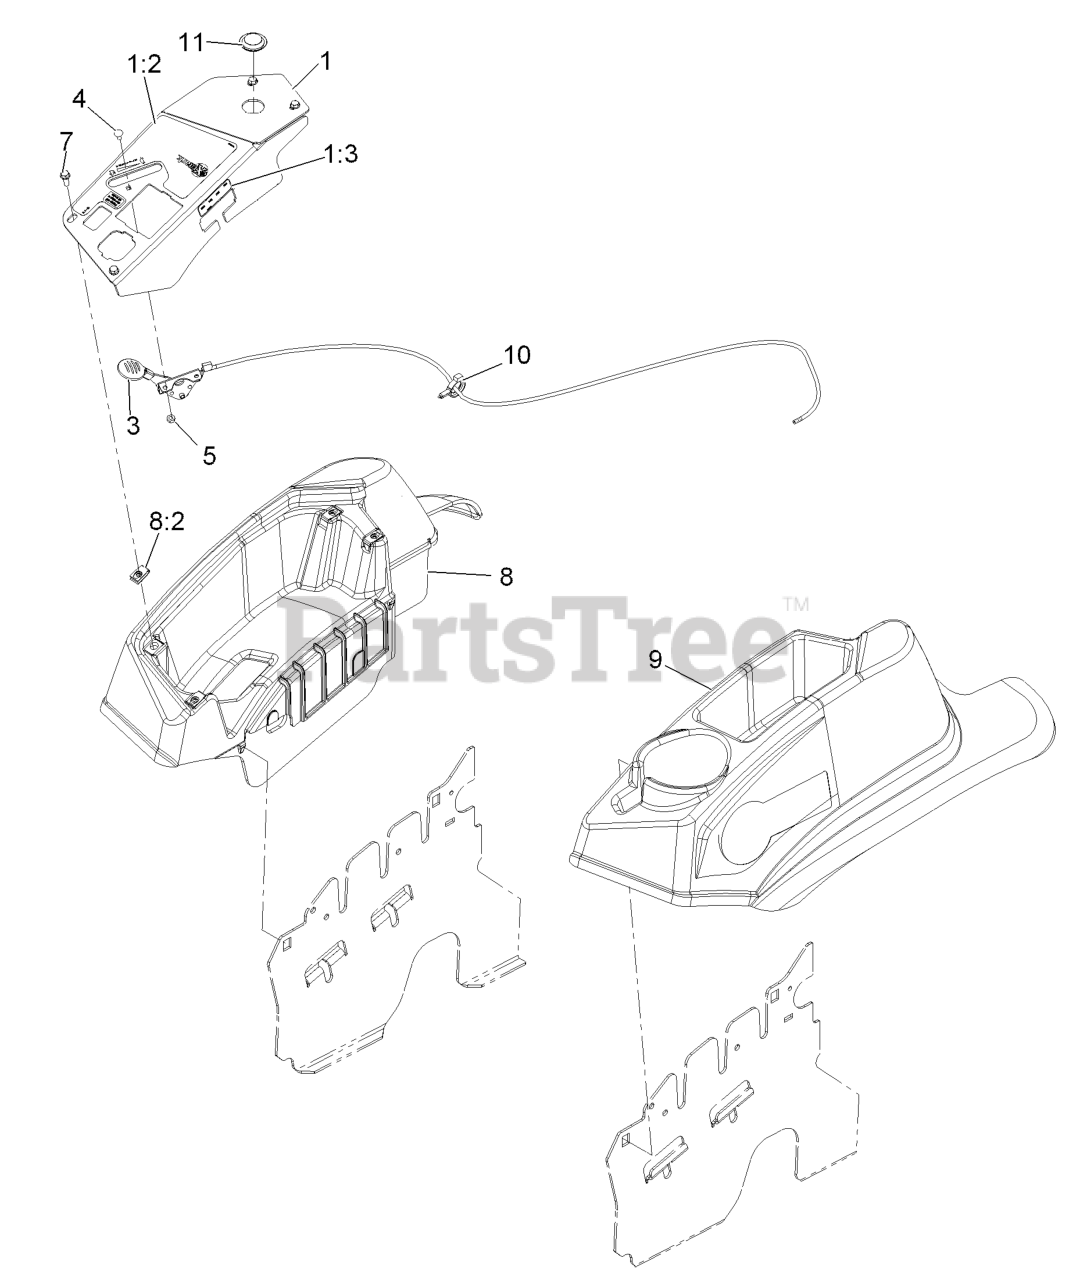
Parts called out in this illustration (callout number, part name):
1	CONTROL PANEL W/DECALS AS
1:2	DECAL,CONTROL PANEL LP
1:3	DECAL-FUSE
3	ASM,THROTTLE CABLE
4	BOLT-CARR
5	NUT-LOCK, NI
7	SCREW-HWH
8	CONSOLE,RH AS ASM
8:2	Nut-Retainer-Panel 1/4-20
9	CONSOLE, LH AS
10	CLAMP-HOSE
11	PLUG-PLASTIC
